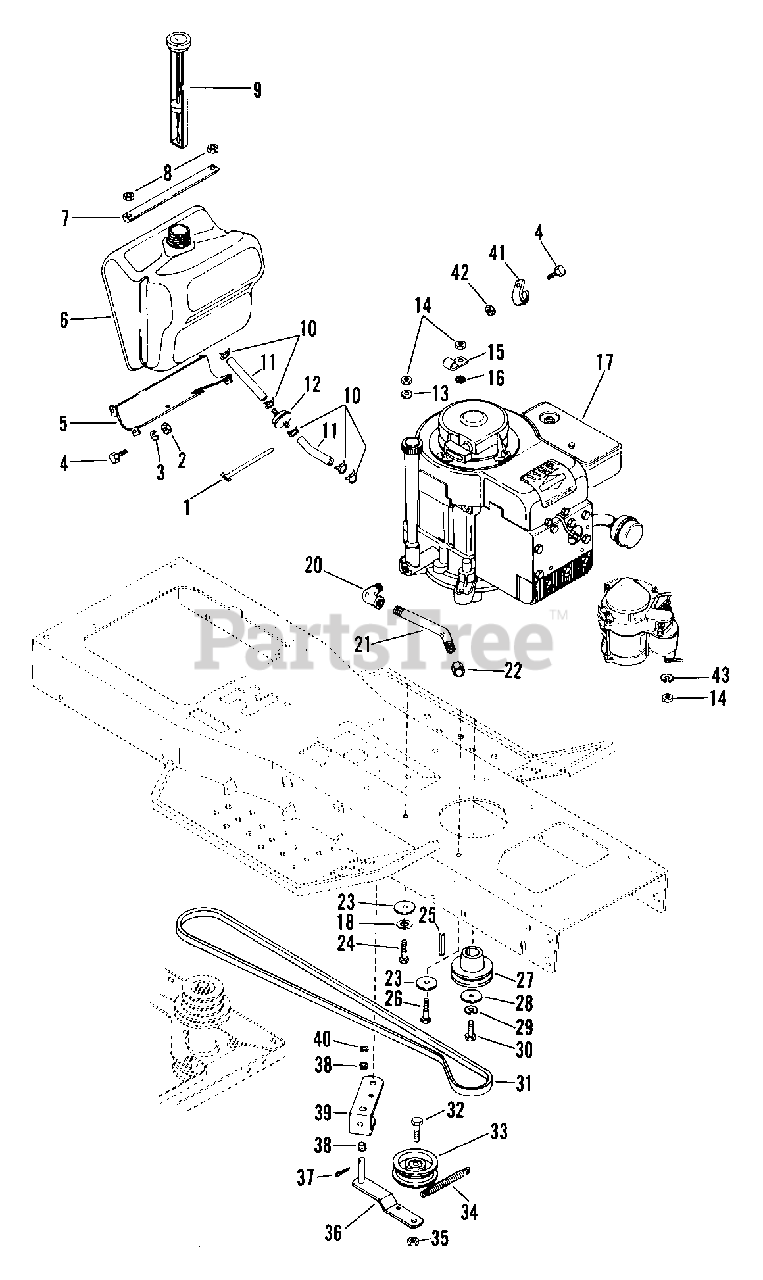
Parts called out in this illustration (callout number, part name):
1	TIE DOWN
2	NUT-HEX .250-20 PL
3	WSHR-LK .250X.077 HVY PL
4	BLT-HEX .25-20X.50 PL GR2
5	LOWER TANK SUPPORT
6	FUEL TANK
7	CLAMP STRAP
8	NUT-LK TOP .250-20 PL
9	FUEL GAUGE
10	CLAMP-HOSE WIR.490/.510X.092#8
11	FUEL LINE
12	FUEL FILTER
13	WSHR-FL-STL.312X.734X.065PL
13	WSHR-LK .312X.097 PL HVY
14	NUT-LK-TOP .312-18 GR C PL
14	NUT M (ND)
15	J-CLAMP
16	WSHR-LK-EXT .313X.030 PL
17	ENGINE-12 HP B&S I.C. QUIET
17	ENGINE - KOHLER CV12.5S OHV
17	ENGINE - KOHLER CV14S OHV
18	WSHR-LK .312X.097 PL HVY
19	SCR-SKH .31-18X.75 PL
20	PIPE FITTING 90 DEG. X 3/8 ELB
21	OIL DRAIN PIPE
22	PIPE CAP
23	WSHR-FL-STL .312X1.62X.13
24	BLT-HEX .31-18X1.50 PL GR5
25	KEY-STR .25X2.0X.25
26	BLT-HEX .31-18X1.75 GR5
26	BLT-HEX M8 X 1.25X22 PL GR5
27	ENGINE SHEAVE
28	WSHR-FL-STL .469X1.380X.125
29	WSHR-LK .438X.133 HVY
30	BLT-HEX .44-20X1.00 GR5
30	BLT-HEX M10 X 1.5X28
31	V-BELT, 4L-RAW EDGE
32	BLT-HEX .38-16X1.50 PL GR5
33	IDLER-FLAT 2.75 X .38 DAYCO
34	SG-TENS .080X.470X4.88 WLD 30
35	NUT-LK TOP .375-16 GR C YWZC
36	IDLER ARM
37	PIN-COTR .12X1.0 PL
38	BSHG-FLG .372X.500X.312X.625NY
39	IDLER PIVOT
40	WSHR-FL-STL.406X.812X.065PL
42	NUT-LK-FLG .250-20 PL
43	WSHR-LK .313X.078 PL MED
